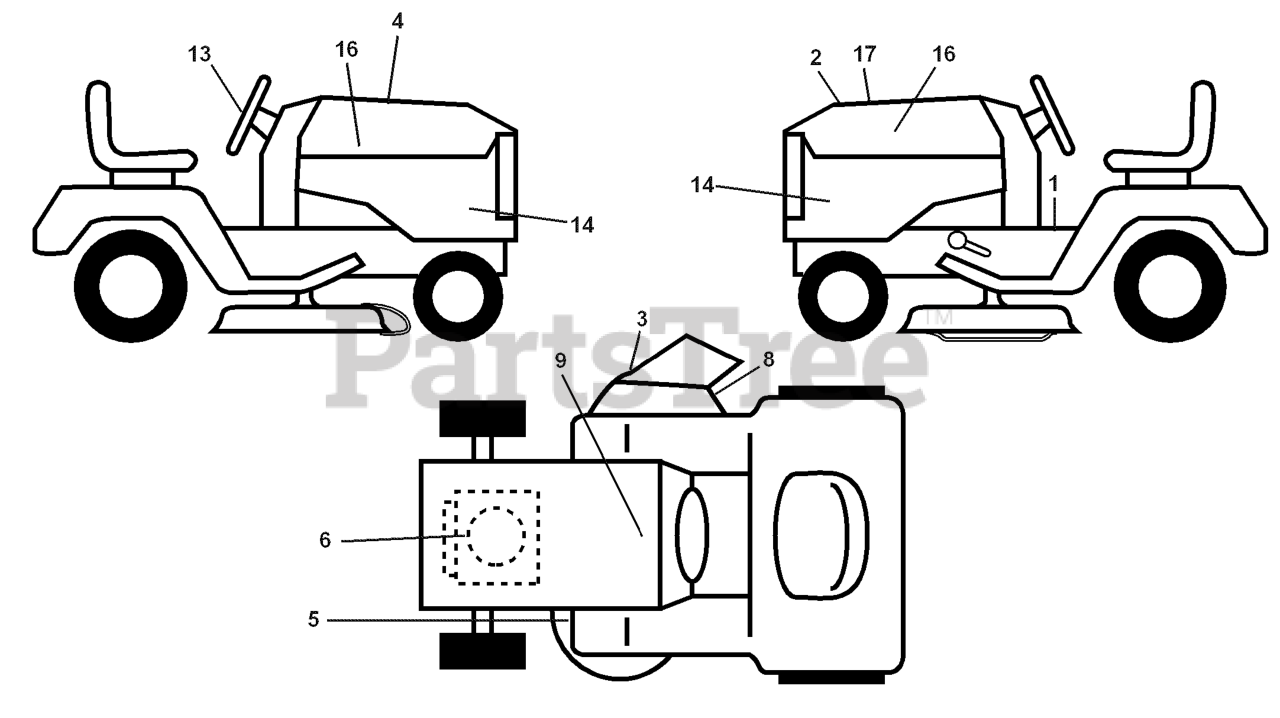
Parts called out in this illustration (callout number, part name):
1	DECAL.FENDER.OPER.TEX.
2	DECAL.HOOD.TOP.INSERT.
3	DECAL.WARN.KEEP.HAND.AWAY
4	DECAL HOOD CUST. RESP.
5	DECAL CLUTCH/BRAKE
6	DECAL.ENG.B&S.24HPINTK.LP.GEN
8	DECAL.MOWER.SCH.48/54
9	DECAL BTRY SYMBOLS
13	DECAL.WHEEL.STRG.LGN.H
14	DECAL PANEL
16	DECAL.HOOD.NAMELOGO.HUSQ
17	DECAL, REPLACEMENT
